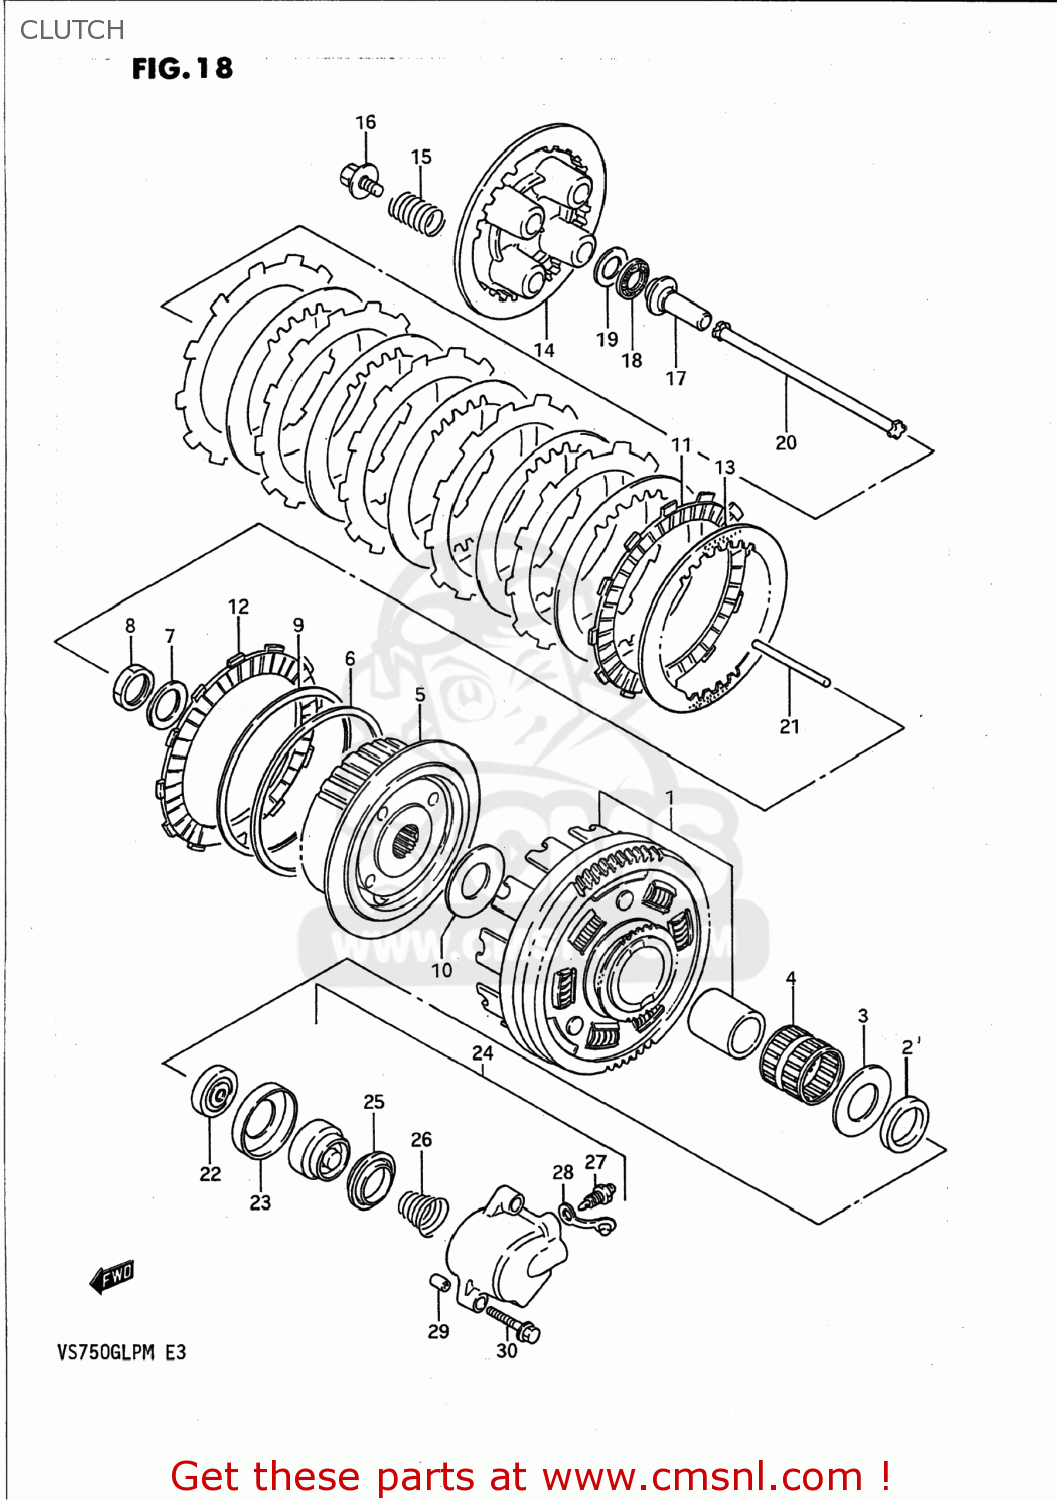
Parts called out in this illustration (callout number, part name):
1	GEAR ASSY,PRI DRIVEN(NT:71)
2	SPACER(25X38X6.5)
3	WASHER(25X50X2.5)
4	BEARING(35X40X35.8)
5	HUB COMP,CLUTCH SLEEVE
6	SEAT,WAVE WASHER(T:1.4)
7	WASHER
8	NUT
9	WASHER
10	WASHER(25X50X2.5)
11	PLATE,CLUTCH DRIVE (NAS)
12	PLATE,CLUTCH DRIVE(T:3.5) (NAS)
13	PLATE,CLUTCH DRIVEN(T:1.6) (NAS)
14	DISC,CLUTCH PRESSURE
15	SPRING
16	BOLT
17	PIECE,CLUTCH PUSH
18	BEARING(15X28X2)
19	WASHER
20	ROD,CLUTCH
21	ROD,CLUTCH PUSH,L
22	SEAL,OIL(6X34X11)
23	RETAINER,CL PUSH ROD OIL SEAL
24	CYLINDER,CLUTCH RELEASE
25	CUP,CLUTCH CYLINDER
26	SPRING,CLUTCH CYLINDER
27	BLEEDER
28	CAP,BLEEDER
29	PIN
30	BOLT
